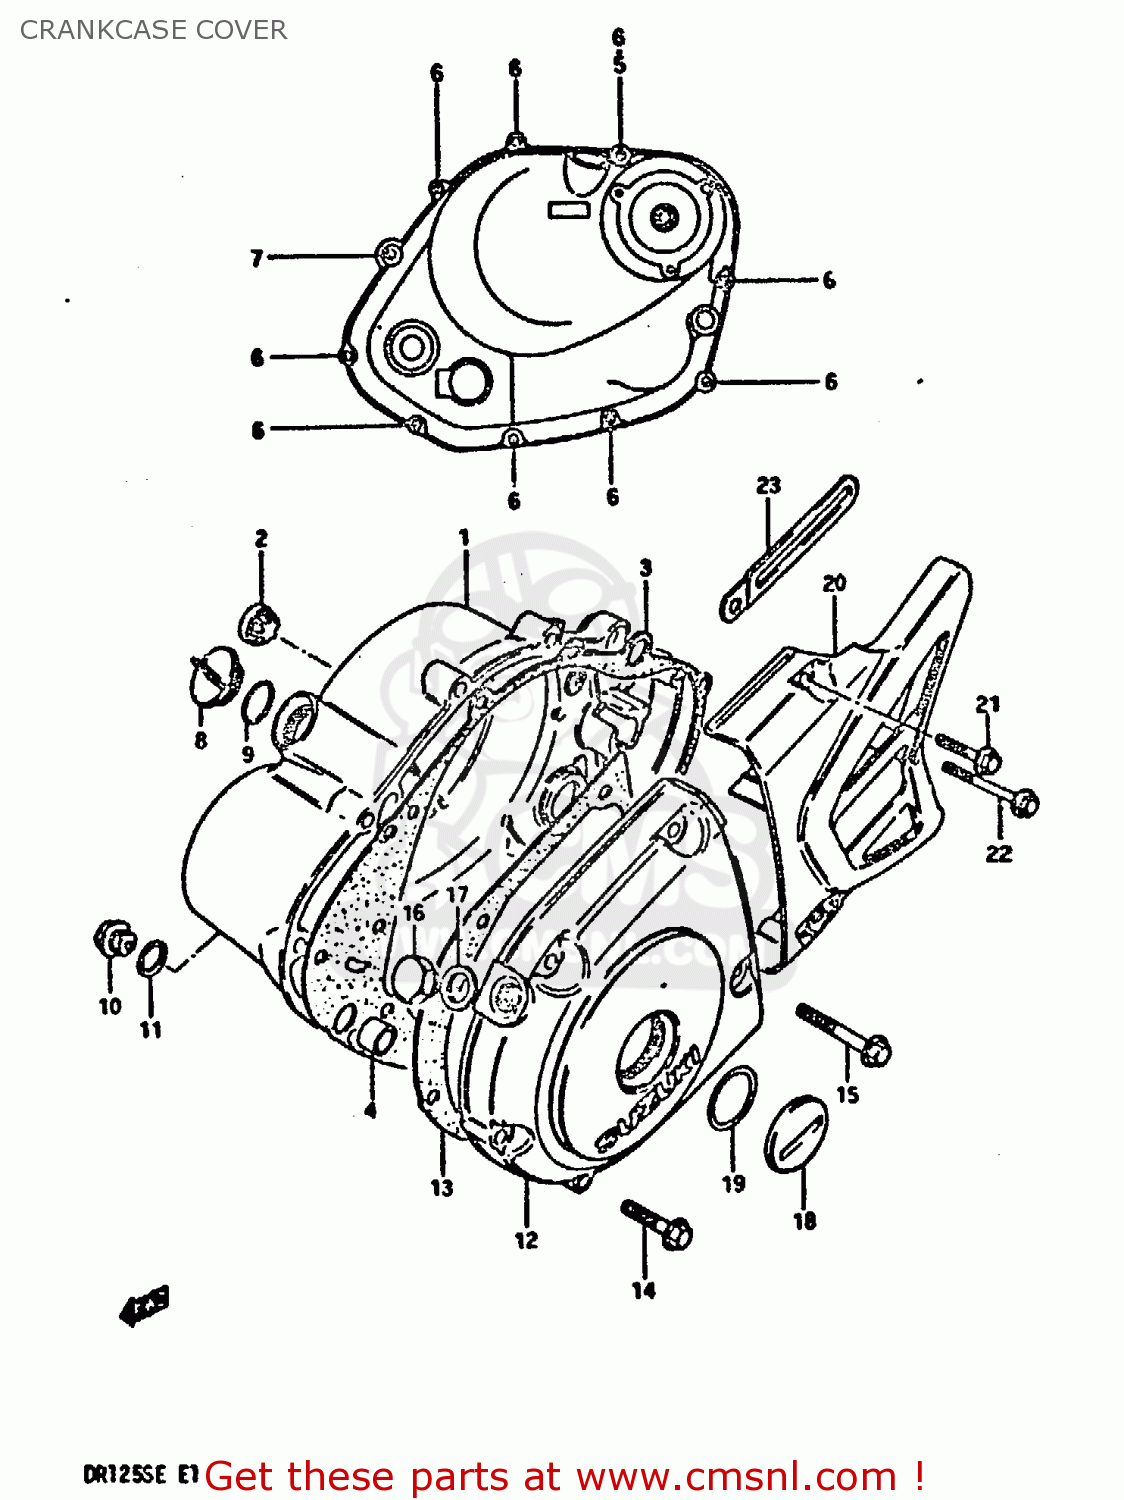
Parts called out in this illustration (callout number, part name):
1	COVER,CLUTCH
2	LENS,OIL LEVEL CHECK
3	GASKET,CLUTCH COVER (MCA)
4	PIN
5	WASHER
6	BOLT 6X30
7	BOLT
8	PLUG
9	O RING
10	PLUG(14X12)
11	GASKET(14X19.2X2) (NAS)
12	COVER,MAGNETO
13	GASKET,MAGNETO COVER (MCA)
14	BOLT 6X30
15	BOLT 6X40
16	PLUG(12X9)
17	GASKET(12.1X16.2X3.7) (NAS)
18	PLUG
19	O RING(D:3.1,ID:22.7)
20	COVER,SPROCKET
21	BOLT
22	BOLT
23	CLAMP
